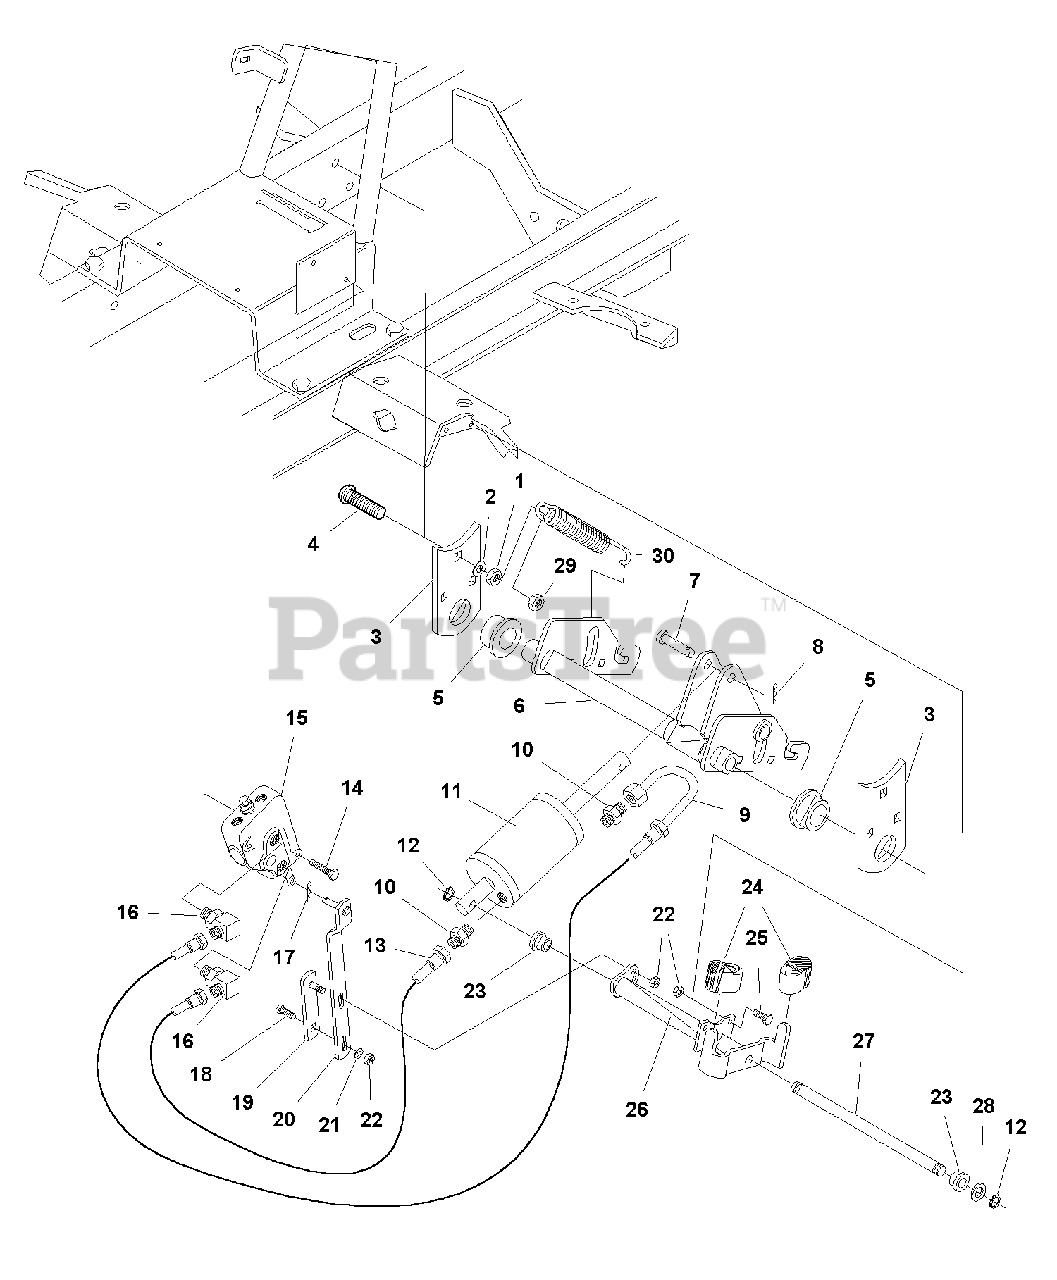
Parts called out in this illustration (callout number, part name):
1	NUT, Hex, Full, 3/8-16
2	LOCKWASHER, 3/8
3	PLATE, Bearing
4	CARRIAGE BOLT, 3/8-16 x 1-1/2
5	BUSHING, Lift
6	SHAFT ASSEMBLY, Lift
7	PIN, Clevis
9	HOSE, Valve to Cylinder (UP)
10	FITTING, Male, Straight
11	CYLINDER, Hydraulic Lift
12	KLIPRING, 1/2
13	HOSE, Valve to Cylinder (Down)
14	CAPSCREW, Taptite, 1/4-20 x 1-3/4
15	VALVE ASSEMBLY, Lift
16	FITTING, 90 Degree
17	HAIRPIN
18	CARRIAGE BOLT, 1/4-20 x 3/4
19	LINK ASSEMBLY, Lower
20	LINK ASSEMBLY, Upper
21	WASHER, Plain, 1/4
22	NUT, Hex, Nylon Lock, 1/4-20
23	BUSHING, Nylon
24	PAD, Hydraulic Lift
25	CAPSCREW, 1/4-20 x 3/4
26	PEDAL ASSEMBLY, Hydraulic Lift
27	SHAFT, Pivot
28	WASHER, Flat, 1/2 x 7/8
29	NUT, Hex Jam, 3/8-16
30	SPRING, Extension
